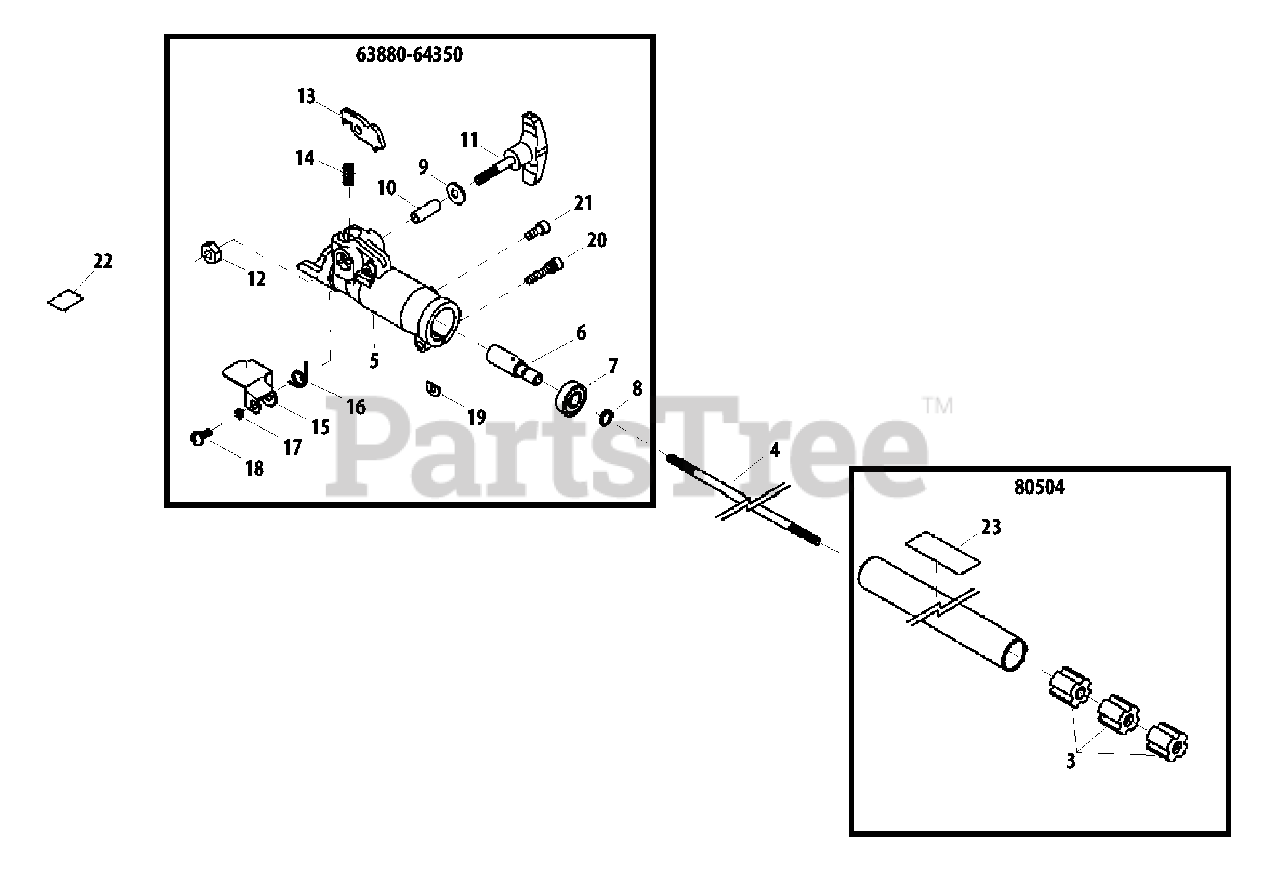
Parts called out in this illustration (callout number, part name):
3	BUSHING
4	MAINSHAFT
5	HOUSING, COUPLER
6	SHAFT, COUPLER
7	BEARING, BALL 609ZZ
8	RING, SNAP
9	WASHER 6
10	COLLAR
11	KNOB, COUPLER SCREW
12	NUT 6
13	LATCH
14	SPRING
15	PROTECTOR, LATCH
16	SPRING, TORSION
17	WASHER 5
18	SCREW M5×12
19	D-WASHER
20	SCREW
21	BOLT 5×12
22	LABEL, LATCH INSTRUCTION
23	LABEL - CAUTION
63880-64350	COUPLER ASSY
80504	MAIN PIPE ASSY
